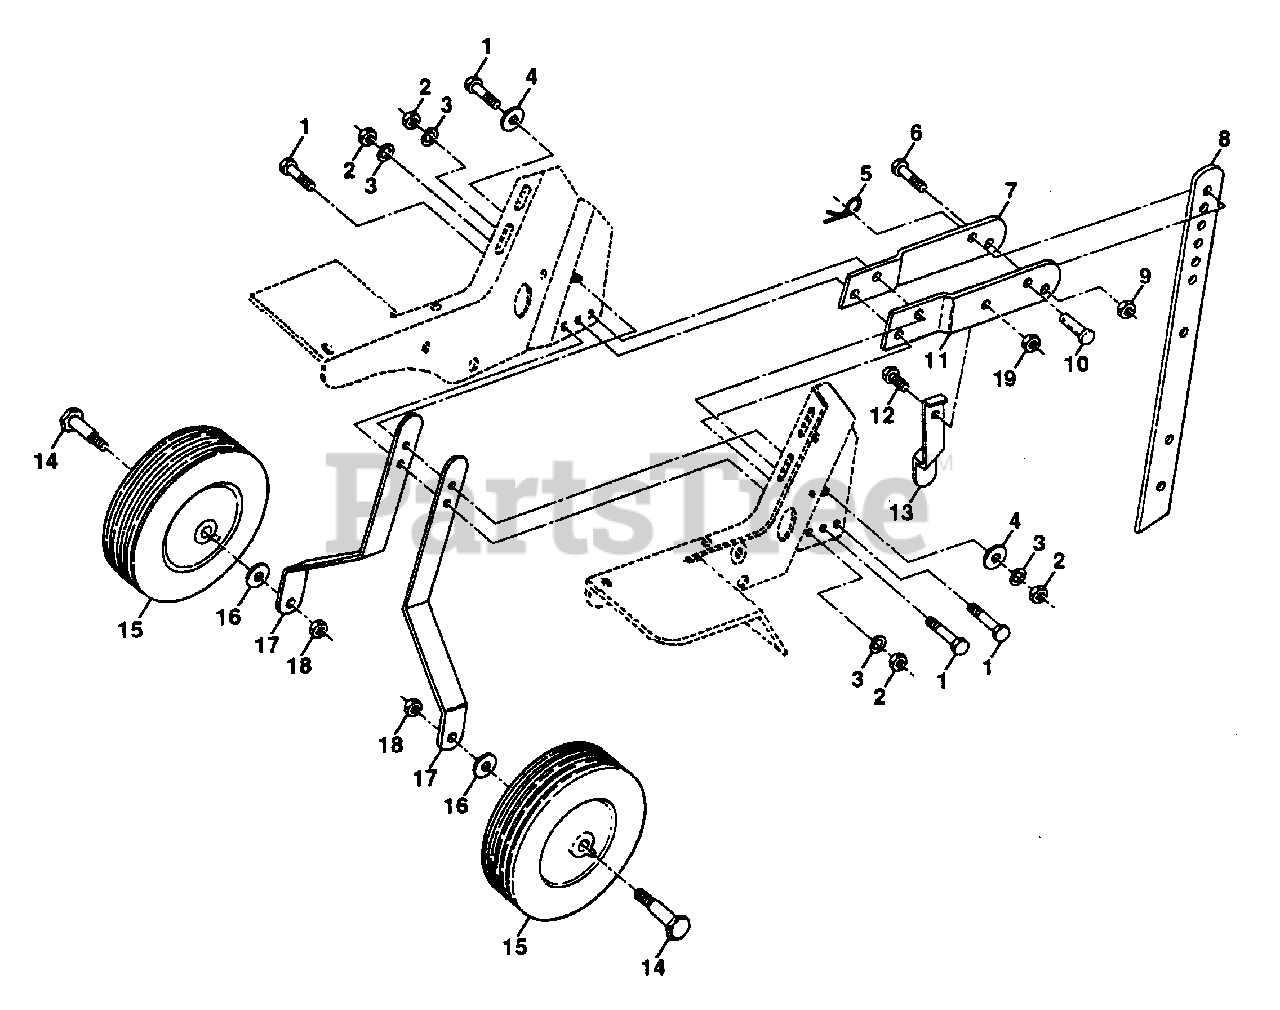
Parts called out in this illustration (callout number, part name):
1	Bolt, Hex 5/16-18 x 1-1/4 (AYP part number)
2	Nut, Hex 5/16-18 (AYP part number)
3	Washer, Lock 5/16 (AYP part number)
4	Washer 3/8 x 7/8 x 14 Ga. (AYP part number)
5	Clip, Hairpin (AYP part number)
6	Bolt, Fin, Hex 3/8-16 x 1-3/4 (AYP part number)
7	Support, Depth Stake, R.H. (AYP part number)
8	Depth Stake (AYP part number)
9	Locknut, w/Insert 3/8-16 (AYP part number)
10	Pin, Clevis (AYP part number)
11	Support, Depth Stake, L.H. (AYP part number)
12	Bolt, Hex 5/16-18 x 3/4 (AYP part number)
13	Spring, Depth Stake (AYP part number)
14	Bolt, Shoulder (AYP part number)
15	Wheel (AYP part number)
16	Washer 13/32 x 13/16 x 11 Ga. (AYP part number)
17	Bracket, Wheel (AYP part number)
18	Nut, Crownlock 3/8-16
19	Locknut, w/Insert 5/16-18 (AYP part number)
